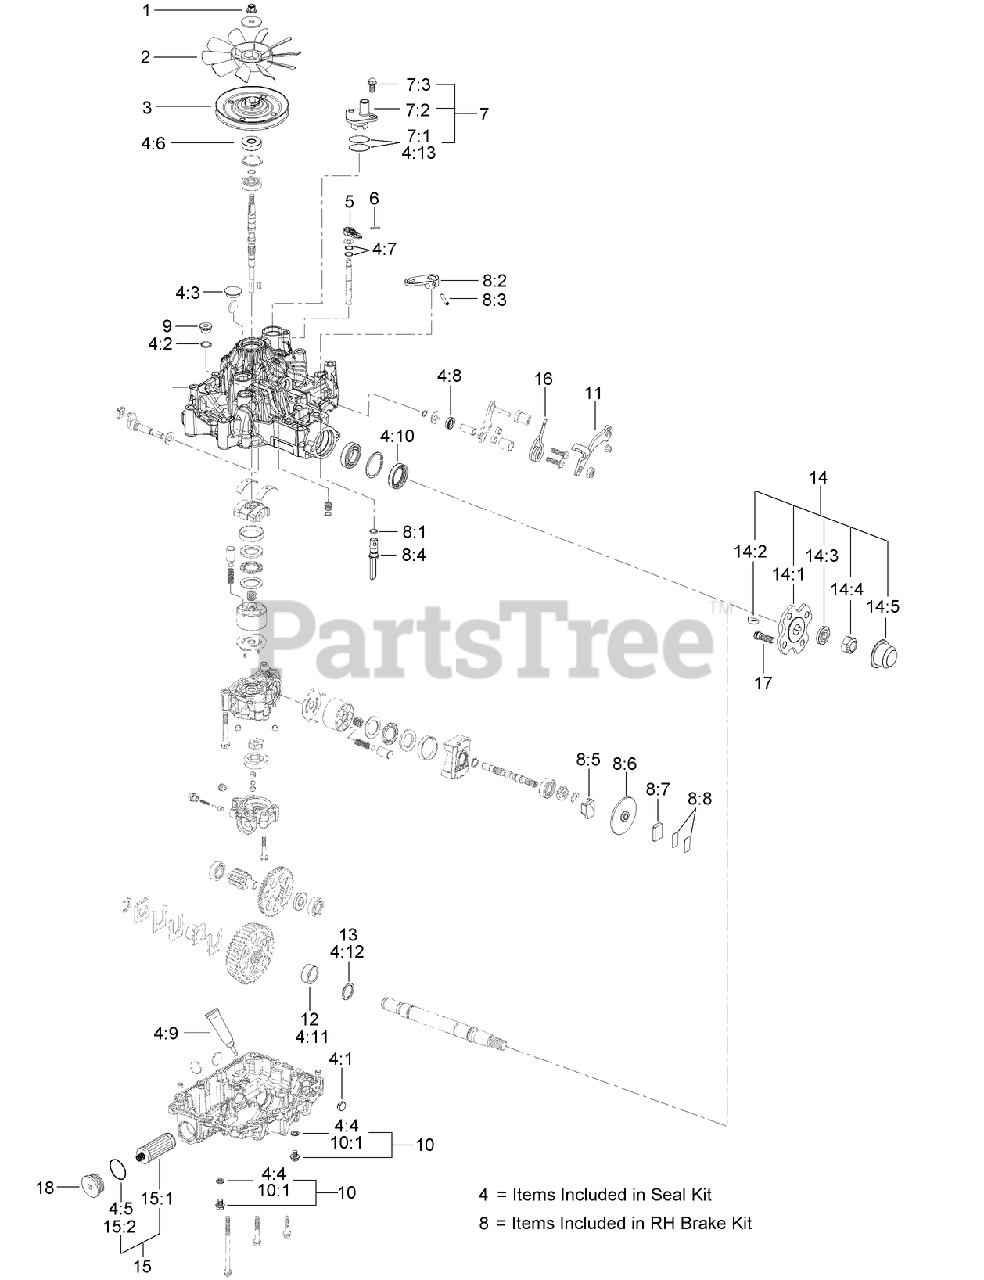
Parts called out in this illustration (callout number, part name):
1	NUT-LOCK
3	PULLEY
4	SEAL KIT
4:1	CAP-SEALING
4:2	O-RING
4:3	CAP-SEAL
4:4	Seal-Washer
4:5	Packing
4:6	SEAL-SHAFT
4:7	Deck ASM
4:8	Deck ASM
4:9	SEALANT
4:10	SEAL-AXLE
4:11	SLEEVE
4:12	WASHER
4:13	Packing
6	LEVER-BYPASS
7	EXPANSION FITTING KIT
7:1	SEAL-FITTING, EXPANSION
7:2	Fitting
7:3	BOLT-FLANGE
8	RH BRAKE KIT
8:1	Deck ASM
8:2	ARM-BRAKE
8:3	Deck ASM
8:4	SHAFT-BRAKE
8:5	ACTUATOR-BRAKE
8:6	DISC-BRAKE
8:7	SHOE-BRAKE
8:8	SHIM KIT
9	CAP-OIL
10	DRAIN BOLT KIT
10:1	Seal-Washer
11	LEVER-CONTROL, RH
12	SLEEVE
13	WASHER
14	AXLE FLANGE KIT
14:1	Deck ASM
14:2	Key-Woodruff
14:3	Deck ASM
14:4	NUT-LOCK
14:5	NUT-CAP
15	HYDRO FILTER KIT
15:1	FILTER
15:2	O-RING
16	SPRING-TORSION
17	STUD-WHEEL
18	CAP-OIL FILTER
